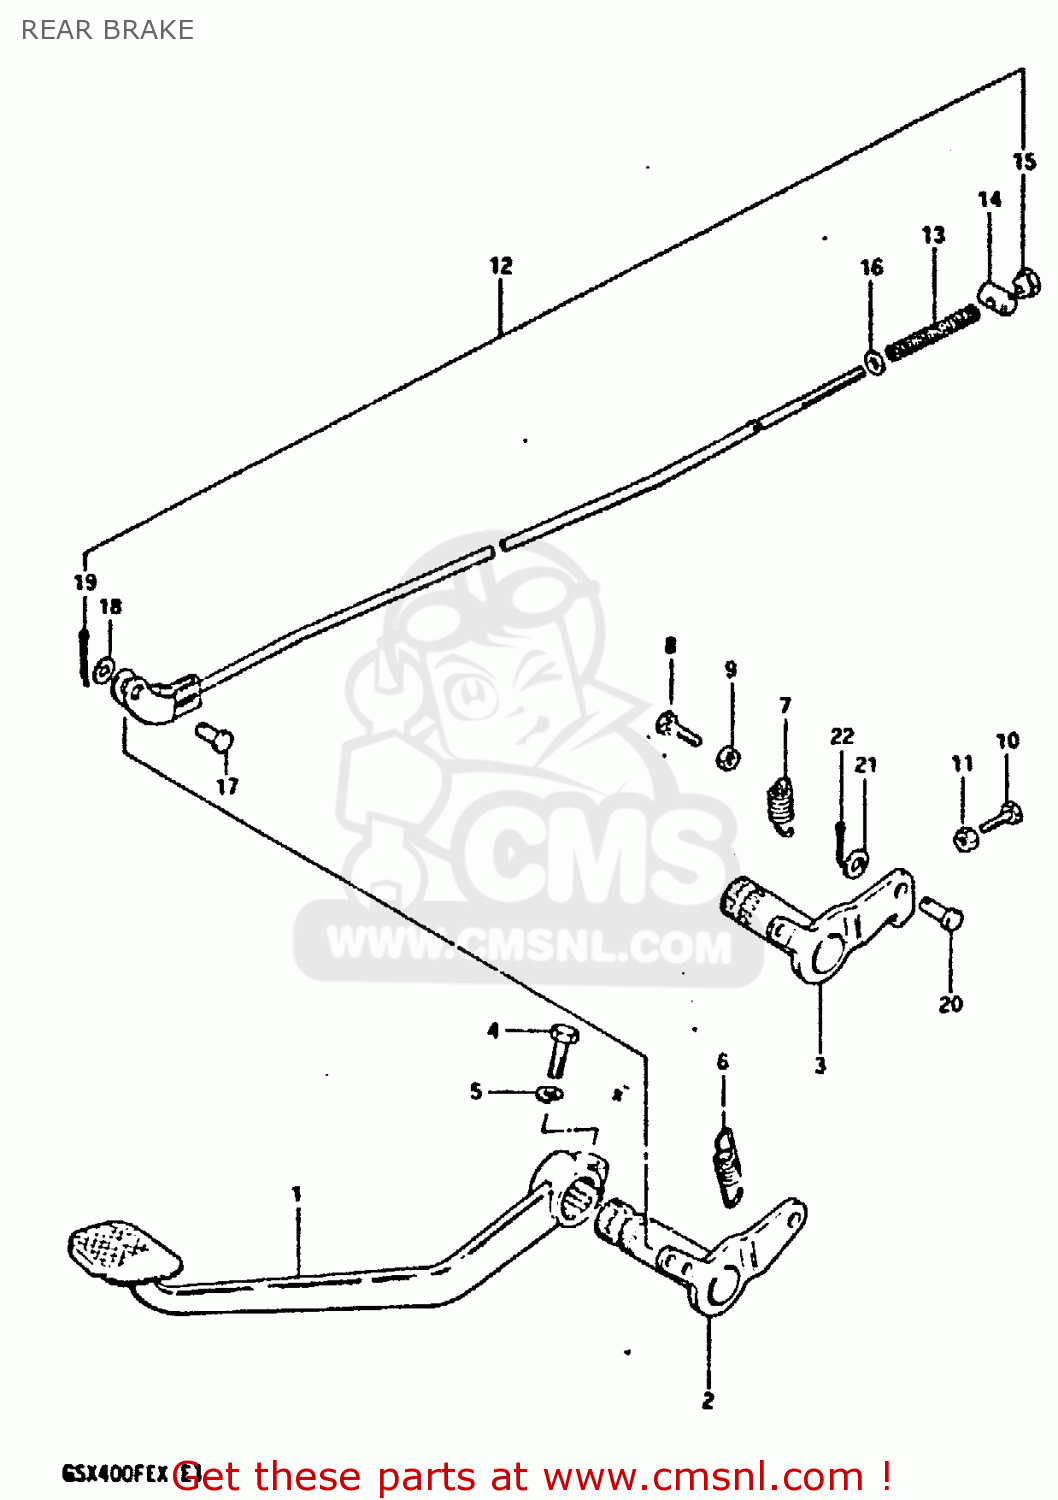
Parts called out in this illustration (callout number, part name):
1	PEDAL, BRAKE
3	ARM, BRAKE PEDAL ROD
4	BOLT
5	LOCK WASHER
7	SPRING
8	BOLT
9	NUT
10	BOLT
11	NUT
20	PIN
21	WASHER
22	PIN
